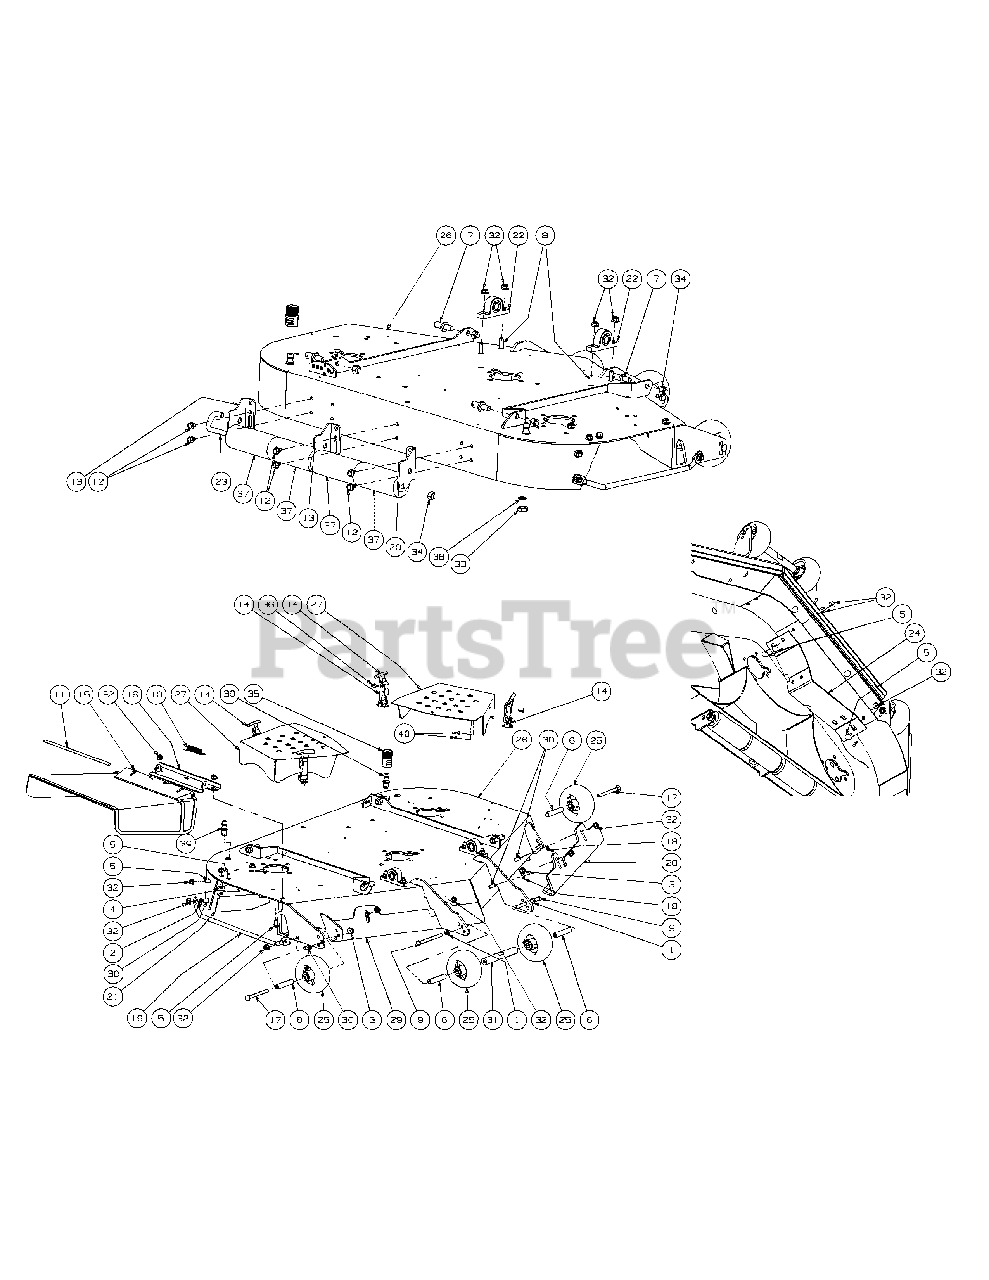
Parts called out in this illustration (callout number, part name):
1	Lock Washer, 3/8
2	Flat Washer, 3/8
3	Flange Lock Hex Nut, 3/8-16
4	Idler Washer
5	Carriage Bolt, 3/8-16 x .75 Lg.
6	Wheel Spacer
7	Pin, 5/8 Dia. x 1.2 Lg.
8	Carriage Bolt, 3/8-16 x 1.25
9	Hex Cap Screw, 3/8-16 x 4.50
10	Torsion Spring, 0.4ID x 2.16Lg
11	Chute Deflector Rod
12	Hex Index Washer Screw, 3/8-16, .05
13	Deck Roller Mount Bracket
14	T-Handle Latch Draw
15	Deflector Chute
16	Deflector Chute Bracket
17	Carriage Bolt, 3/8-16 x 4.00
18	Push Retainer
19	Finger Guard
20	Deck Roller Mounting Bracket, Right Hand
22	Pillow Block, Steel
23	J-Hook w/ Threaded Roller
24	48" Adjustment Baffle
25	Complete Wheel, 5.00 Dia.
26	48" Deck Assembly
27	Deck Belt Cover
28	Left Hand Front Adjustment Skirt
29	Right Hand Front Adjustment Skirt
30	Carriage Bolt, 3/8-16 x 1
31	Ball Wheel Mounting Shaft
32	Lock Nut, Nylon Inster, 3/8-16
33	Hex Nut, M16-1.5
34	Lock Nut, Nylon Insert, 1/2-13
35	Water Nozzle Adaptor
36	Phillips Head Screw, #10-32 x 1/2
37	Front Roller
38	Lock Washer, 17 x 23.8 x 1.95
39	Deck Water Nozzle
40	Lock Nut, Nylon Insert, #10-32
